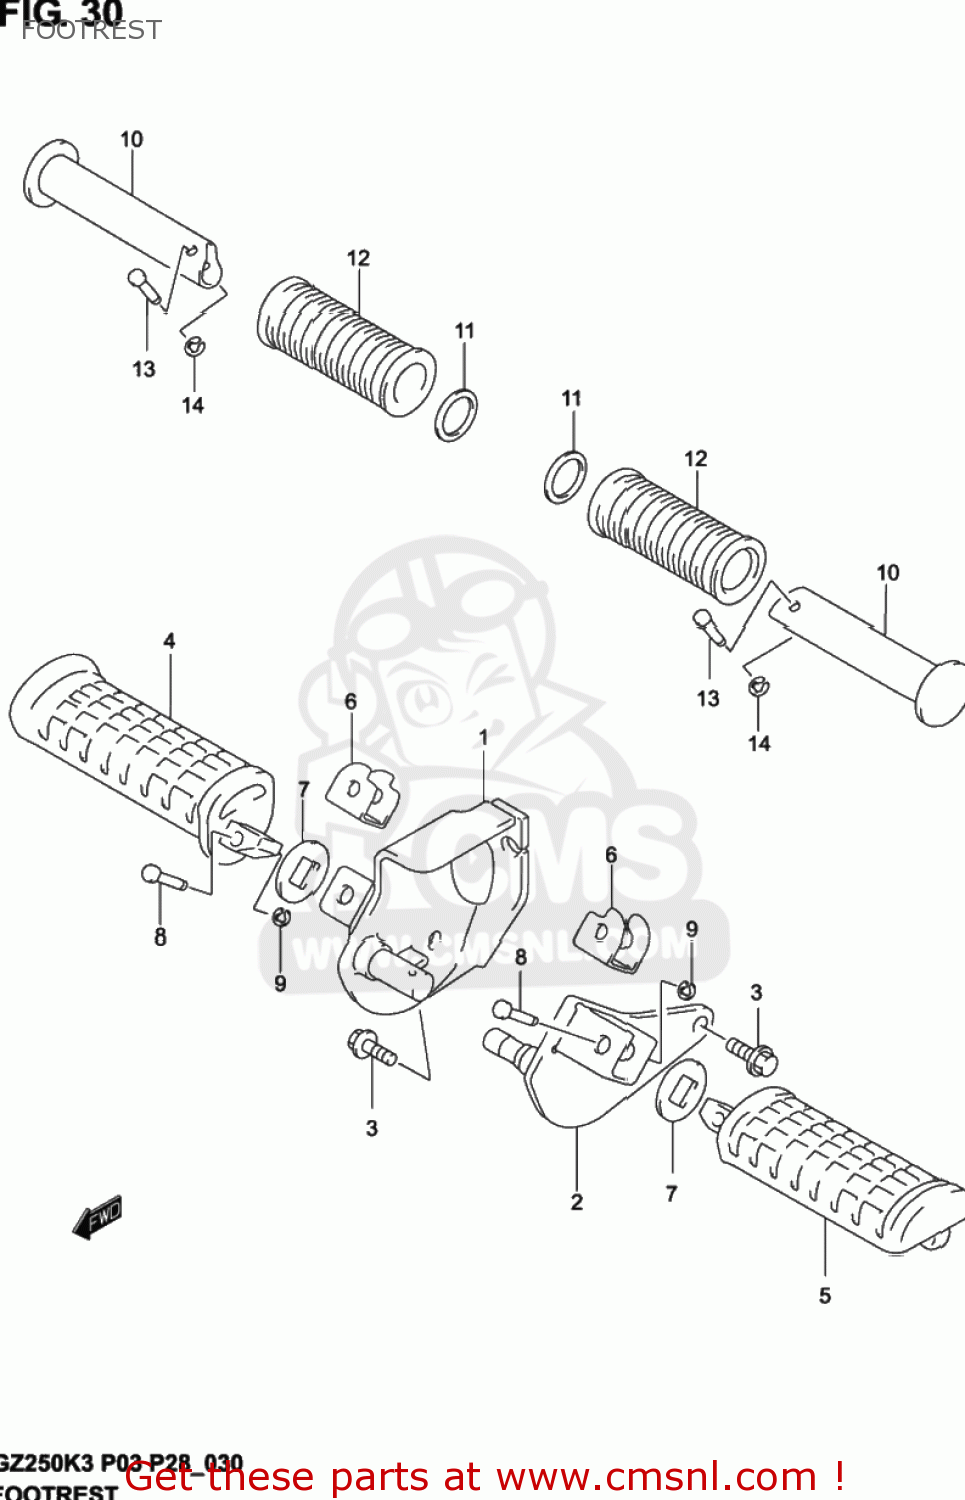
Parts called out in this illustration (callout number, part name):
1	BRACKET COMP.
2	BRACKET COMP.
3	BOLT
4	RUBBER COMP. F
5	RUBBER COMP. F
6	CUSHION,FR FOOTREST
7	WASHER,FOOTREST RUBBER
8	PIN
9	E-RING
10	BAR,FOOTREST RUBBER
11	WASHER(19.5X32X2)
12	RUBBER PILLION
13	PIN,PILLION FOOTREST
14	E-RING
